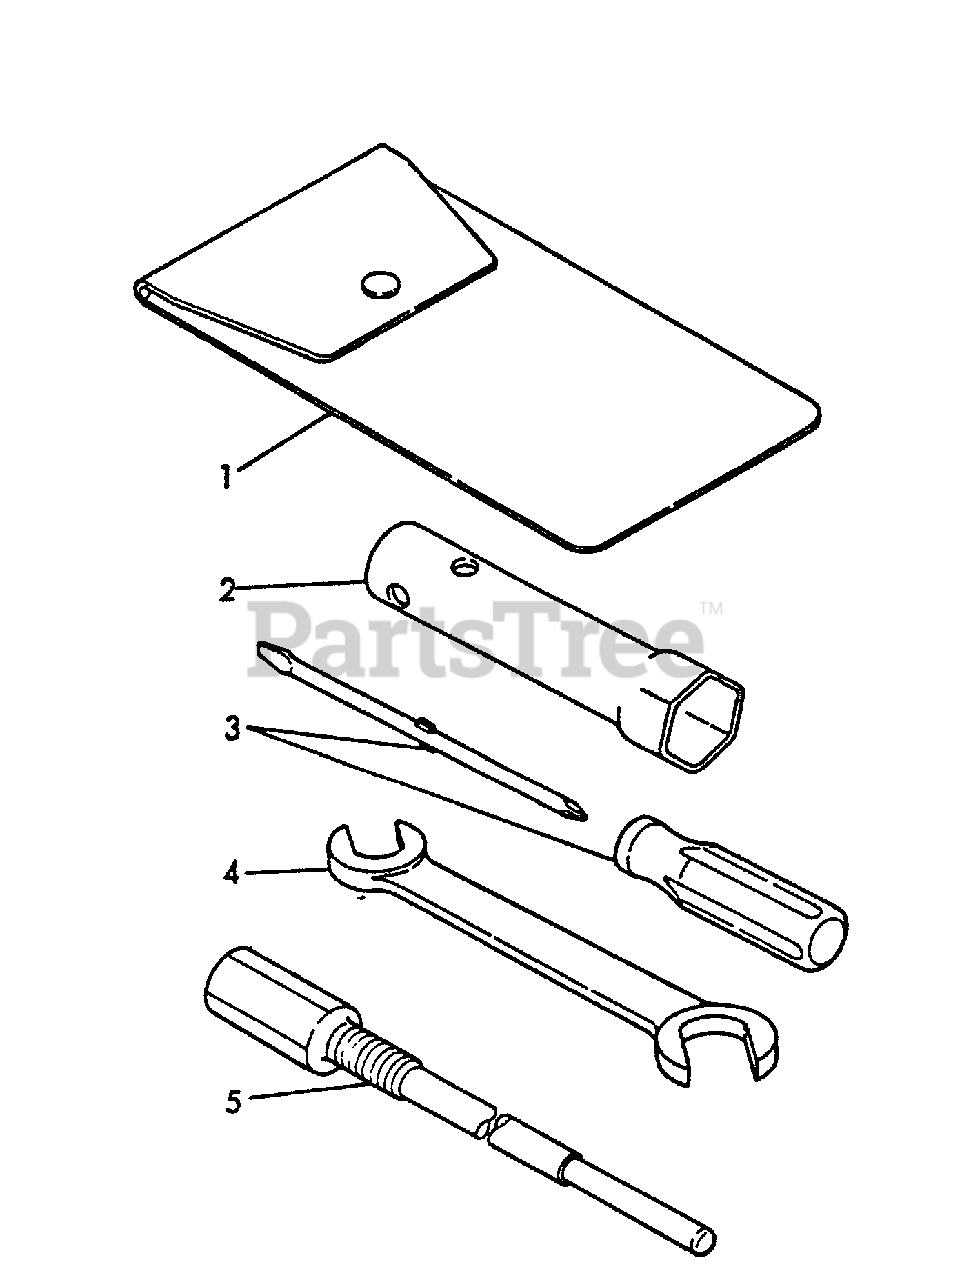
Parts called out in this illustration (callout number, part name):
1	BAG, TOOL
2	SOCKET WRENCH - 21mm
3	SCREWDRIVER
4	SPANNER - 10X12mm
5	REMOVER, ROTOR
